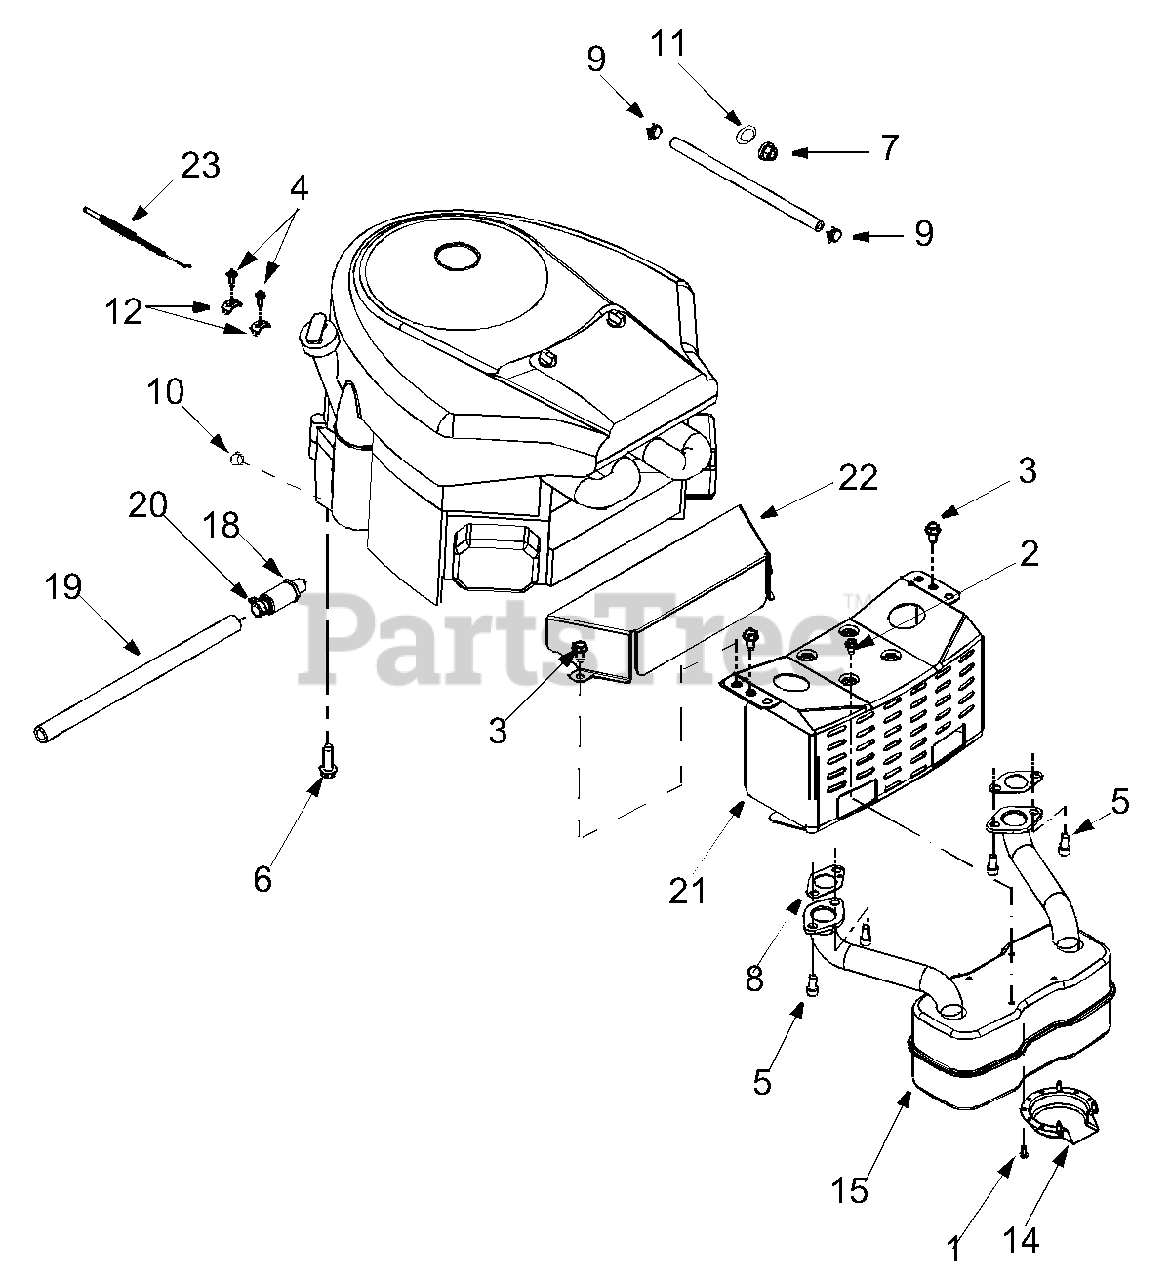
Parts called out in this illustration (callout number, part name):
1	Self-tapping Screw, #8-18 x .5
2	Self-tapping Screw, 1/4-20 x .5
3	AB Screw, 5/16-12 x .75
4	Screw, #10-32 x .625
5	Socket Cap Screw, 5/16-18 x .625
6	Self-tapping Screw, 3/8-16 x 1.25
7	Hex Nut, 3/8-16
8	Exhaust Gasket
9	Hose Clamp
11	Flat Washer
12	Casing Clamp
13	Fuel Line Hose
14	Muffler Deflector
15	Muffler, Twin Inlet
16	RH Exhaust Pipe
17	LH Exhaust Pipe
18	Oil Drain Valve
19	Oil Drain Hose
20	Oil Drain Cap
22	Engine Heat Shield
23	Throttle Cable
